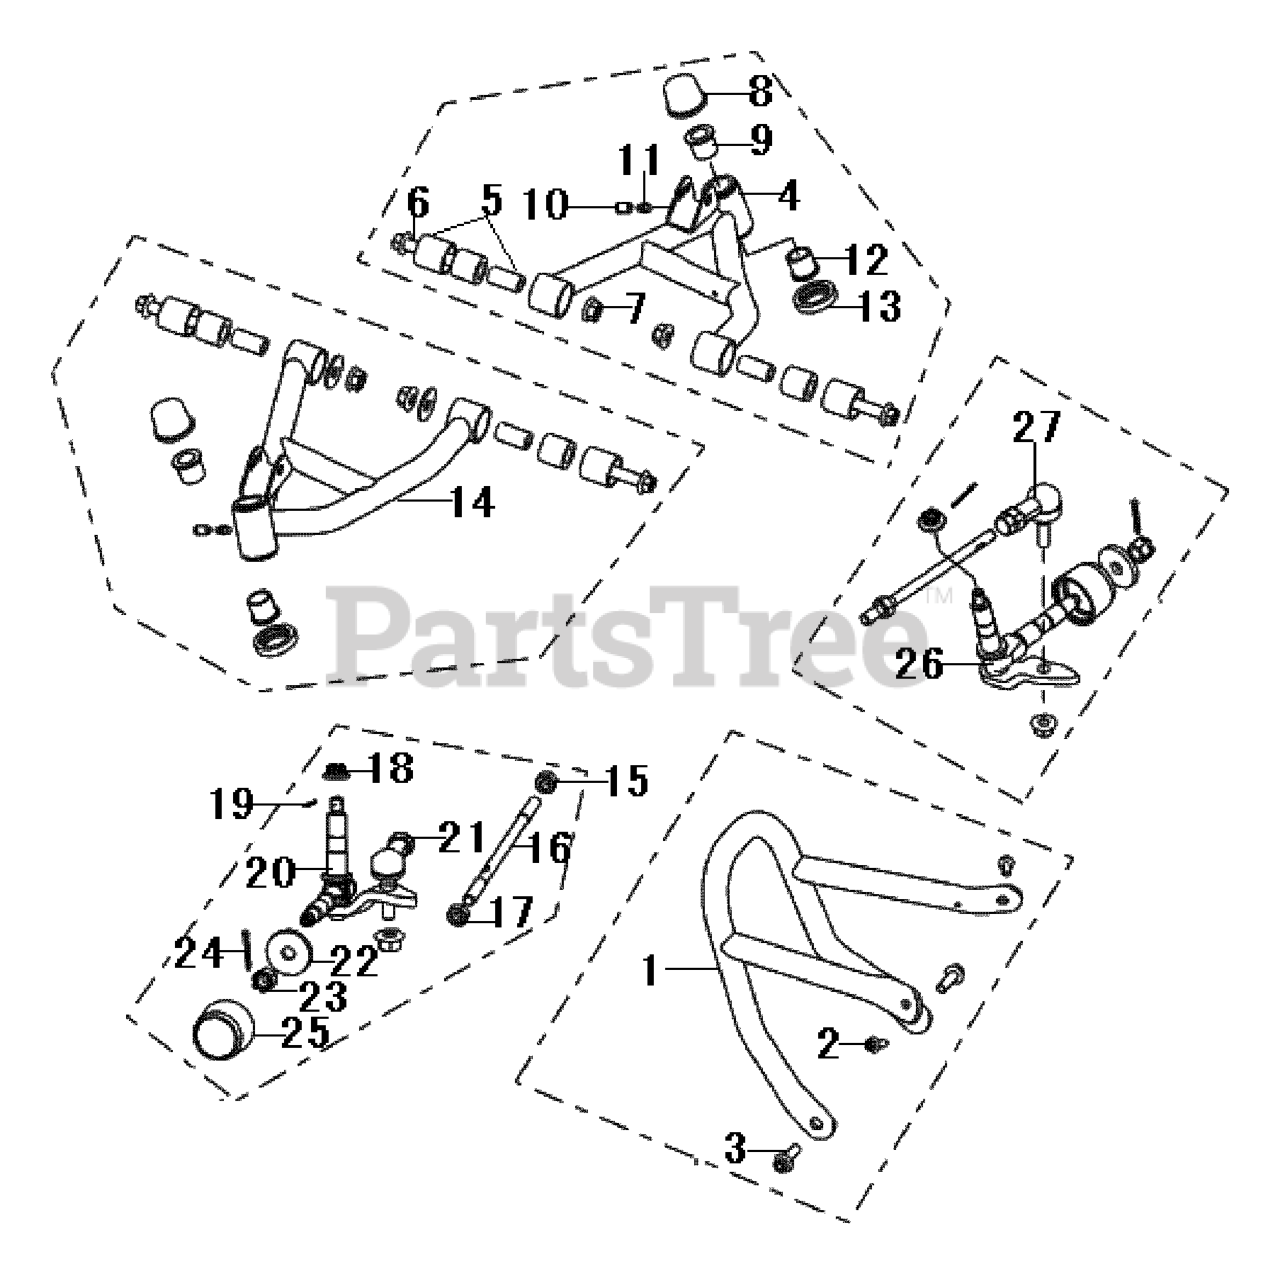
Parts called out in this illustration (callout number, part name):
1	FRONT GUARD
4	A-ARM, RIGHT
5	BUSHING ASSY.
8	DUST CAP
9	BUSHING
10	GREASE FITTING CAP
11	GREASE FITTING
12	BUSHING
14	A-ARM, LEFT
16	TIE ROD
19	SPLIT PIN
20	SPINDLE ASSY, LEFT
21	BALL JOINT
23	NUT, CASTLE
24	PIN, COTTER
25	HUB CAP
26	SPINDLE ASSY., RIGHT
27	BALL JOINT
